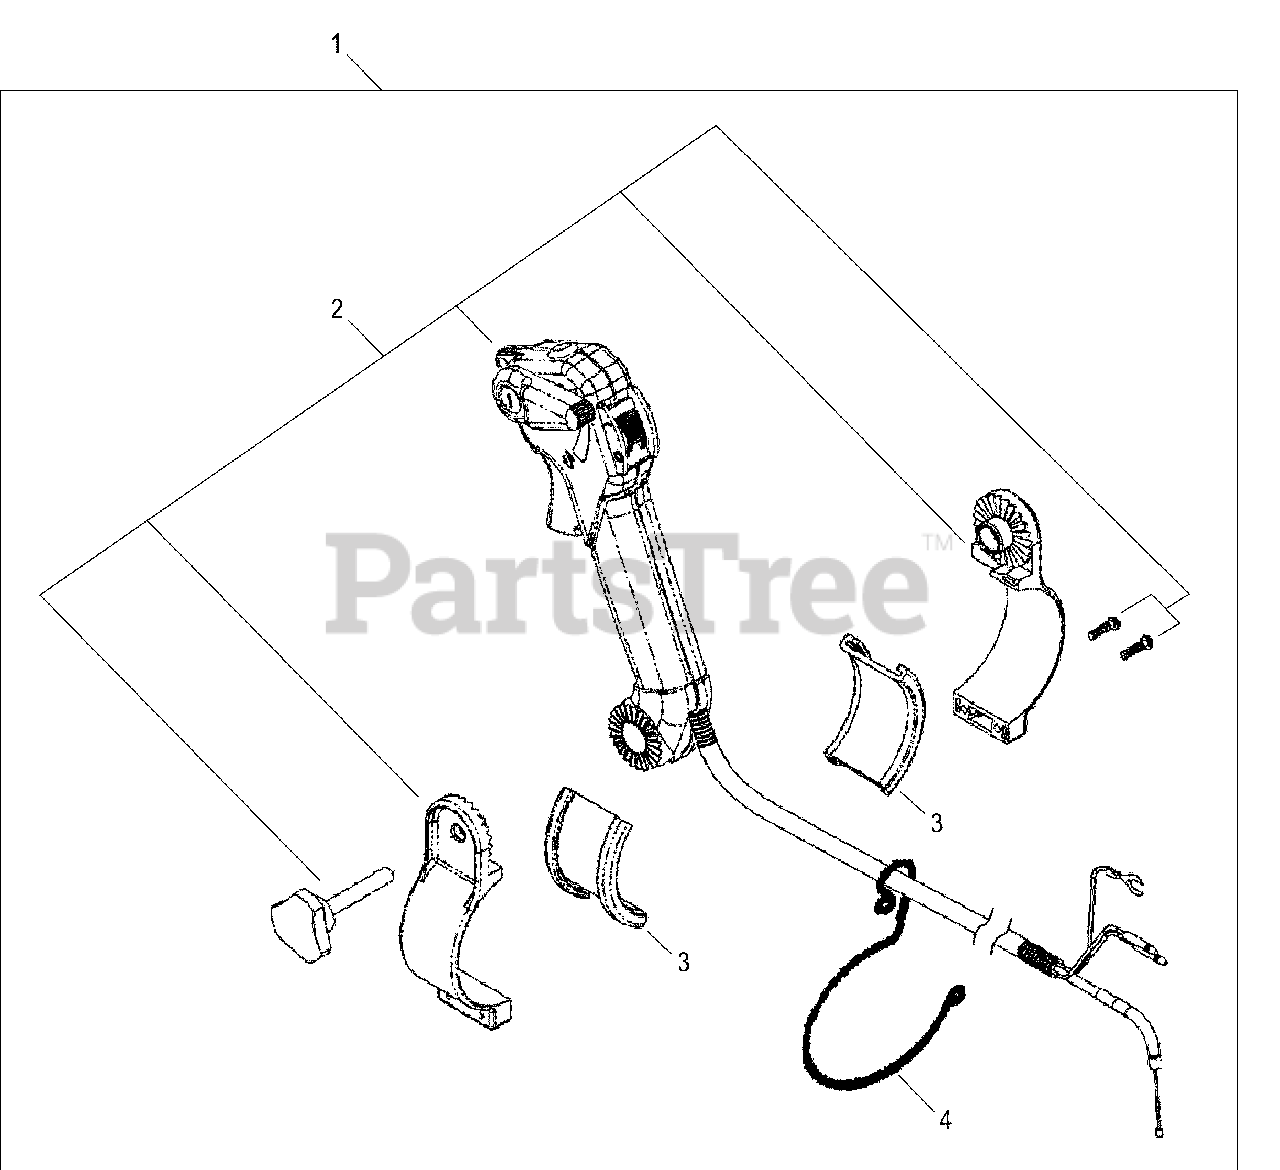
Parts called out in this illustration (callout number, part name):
1	THROTTLE CONTROL KIT
2	THROTTLE CONTROL ASSY
3	SPACER
4	HOLDER, THROTTLE CABLE
